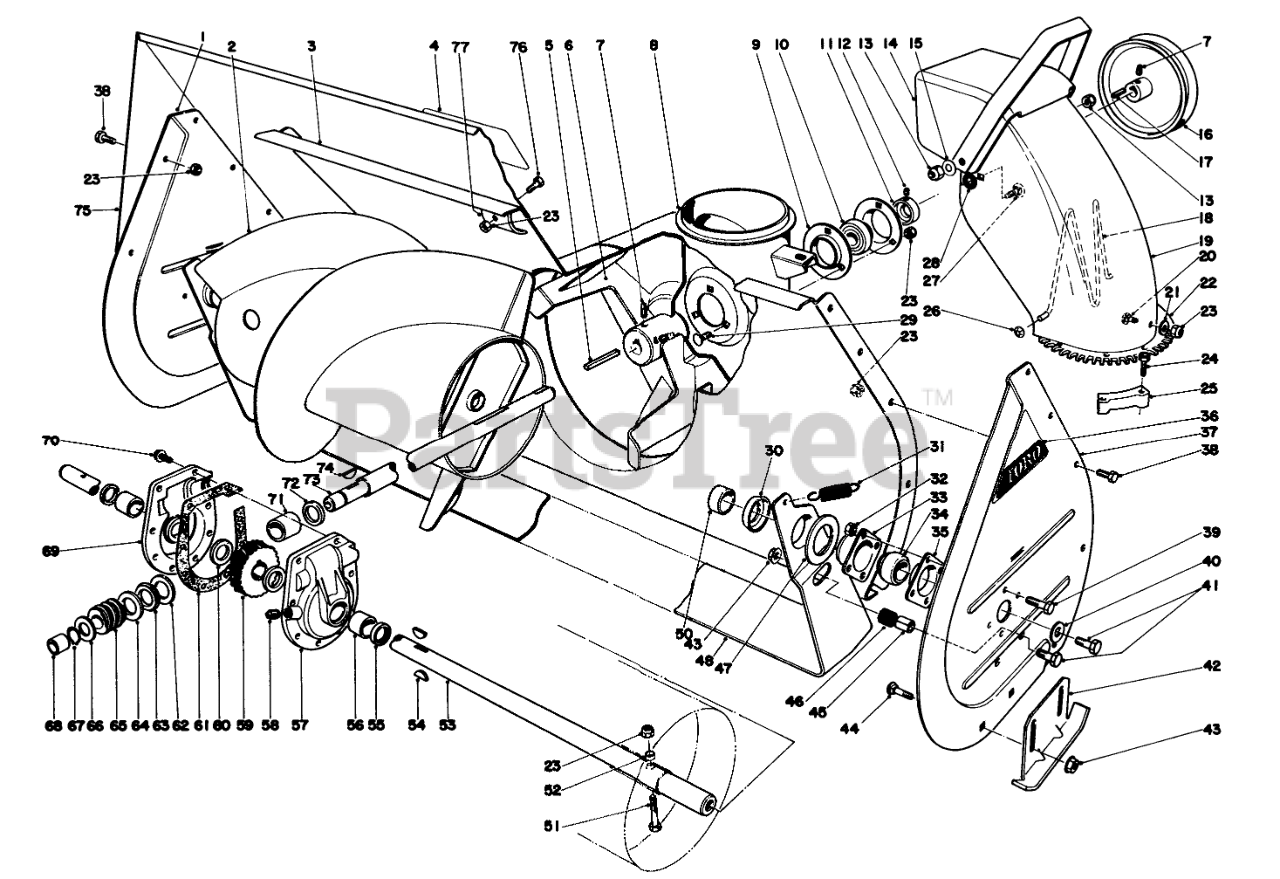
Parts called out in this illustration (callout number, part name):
1	RH AUGER SIDE PLT R
2	RH AUGER WA 26" B
3	AUGER HSG WA 26" R
4	Decal
6	IMPELLER ASM
7	SCREW-SET, SQH
8	CHUTE RING
9	BRG FLANGE
10	BALL BRG W/COLLAR
11	EXT LOCKING COLLAR
12	SCREW-HSH
13	NUT-LOCK, CONE
14	Deflector
15	WASHER-BELLEVILLE
16	1/2 X 9.5 DIA PULLEY
17	SQUARE KEY
18	WIRE-CHUTE
19	Upper Chute
20	SCREW-CARR
21	WASHER-PLAIN
22	Swivel Plate
23	NUT-LOCK, NI
24	SCREW-SPECIAL
25	RETAINER-CHUTE
26	NUT-PUSH
27	SCREW-CARR
28	WASHER-RUBBER
29	BOLT-CARR
30	Positioner-Scraper
31	SPRING-TENSION
32	NUT-LOCK, CONE
33	BEARING-FLANGE, FRONT
34	BEARING
35	BEARING-FLANGE, REAR
36	AUGER SIDE PLT DECAL
37	LH AUGER SIDE PLT R
38	SCREW-HH
39	SCREW-HH
40	WASHER
41	SCREW-HH
42	AUGER SKID WA R
43	NUT-HF
44	SCREW-CARR
45	SCRAPER STOP SPACER
46	SCRAPER STOP CUSHION
47	SCRAPER BLADE SPACER
48	SCRAPER BLADE 26 R
50	AUGER SPACER
51	Auger Bolt
52	SPACER-HUB, AUGER
53	26 AUGER SHAFT
54	KEY-WOODRUFF
55	SEAL-OIL
56	BUSHING
57	Gear Case L.H. (Incl. Ref. #55-56)
58	PLUG-PIPE, SQH
59	GEAR-WORM, 27T
60	WASHER-THRUST
61	asket
62	WASHER-THRUST
63	BEARING-THRUST
64	THRUST-WASHER
66	WASHER-THRUST
67	Ring-Snap
68	BUSHING
69	Gear Case R.H. (Incl. Ref. #55-56)
70	SCREW-TAPTITE
71	BUSHING-SPECIAL
72	RING-QUAD
73	SHAFT-IMPELLER
74	KEY-WOODRUFF
75	Auger Extension
76	SCREW-HH
77	SHIELD CLAMP R
